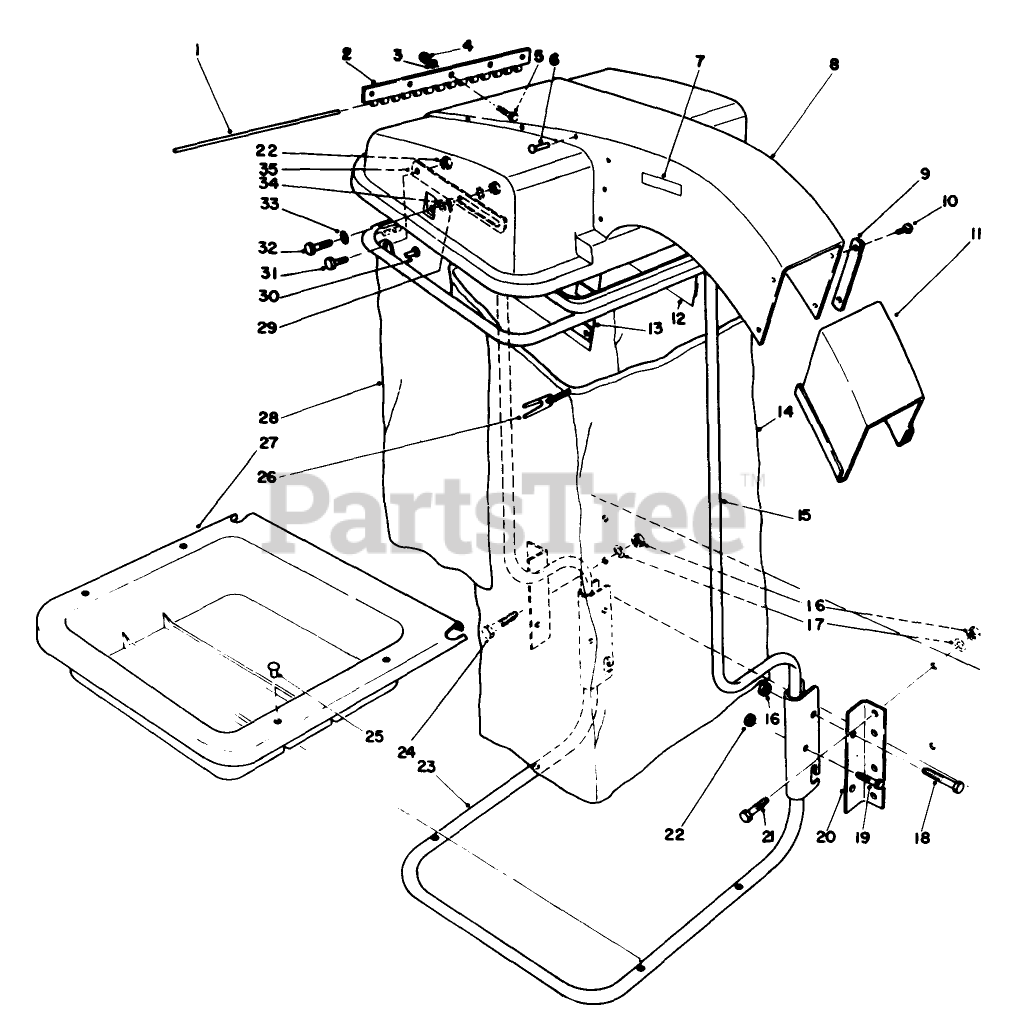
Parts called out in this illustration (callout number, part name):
1	HOOD HINGE PIN
2	Hinge Half
3	WASHER-FLAT
4	NUT-LOCK, NI
6	RIVET-BLIND
7	Decal-Caution
8	Hood Assembly (Incl. Ref. #2-7 & 12-13)
9	PLATE-NUT B
10	SCREW-HSBH
11	Snout Extension
12	Screen Left Hand
13	Screen Right Hand
14	BAG-CLOTH, 32"
15	Support Tube Assembly-(Upper (Incl. Ref. #25 & 28)
16	NUT-LOCK, CONE
17	WASHER-FLAT
18	SCREW-HH
19	SCREW-HH
20	BRKT-FRAME B
21	SCREW-HH
22	NUT-LOCK, CONE
23	Support Tube Assembly-Lower (Incl. Ref. #25 & 27)
24	SCREW-HH
26	BAG CORD FASTENER
27	Tray-Lower
28	Skirt-Bagging Frame
29	SPACER - PIVOT ARM
30	SCREW-HH
31	SCREW-HH
32	WASHER-FLAT
33	WASHER-FLAT
34	Stop-Hood
